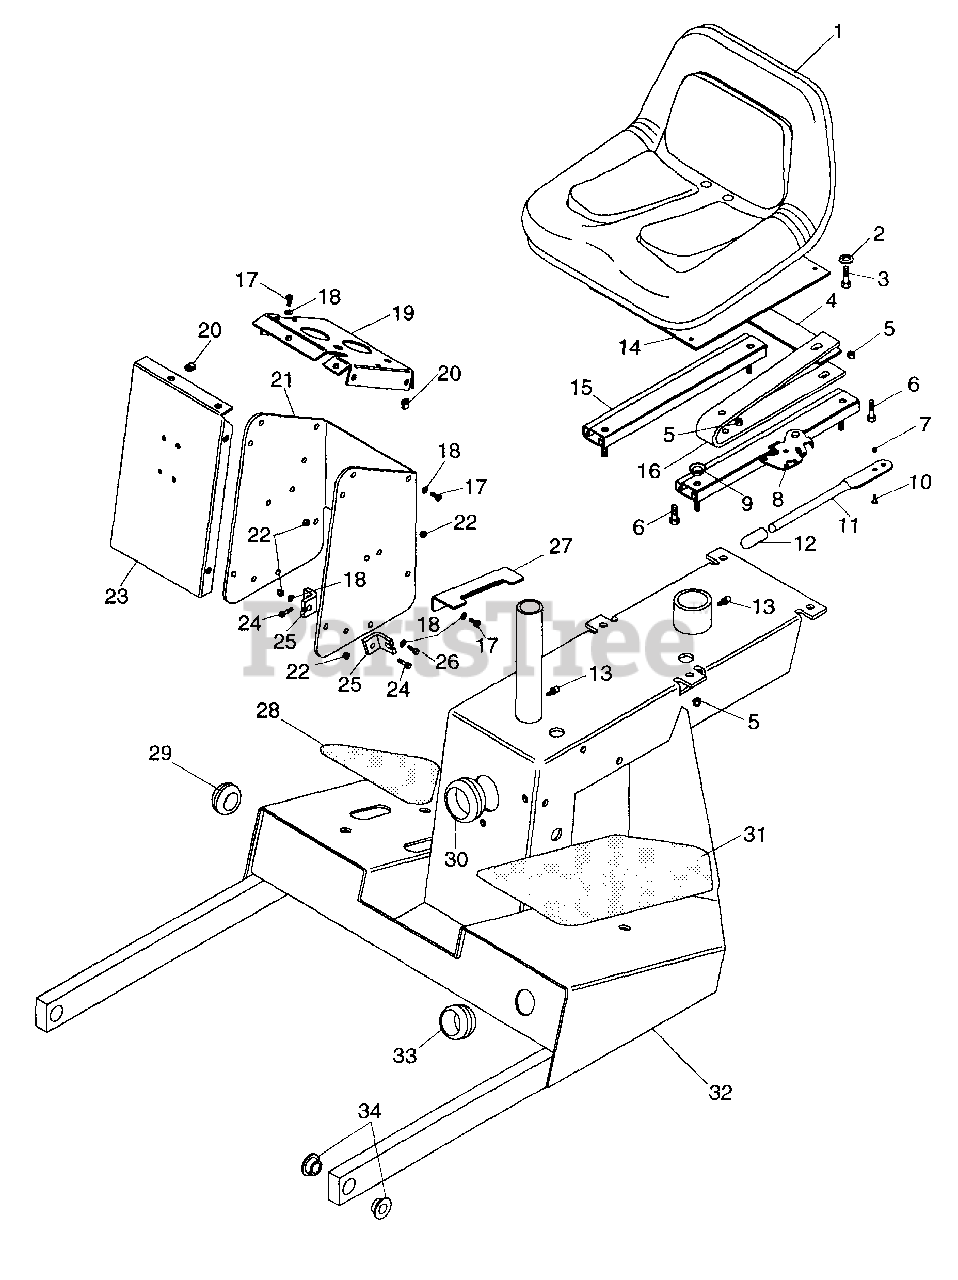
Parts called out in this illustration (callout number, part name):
1	Seat High Back
2	Washer-Lock .313 x .078
3	Bolt-Hex .31-18 x 1.00 Grade 5
4	Bracket, Seat
5	Nut-Locking-Nylon .312-18
6	Bolt-Hex .31-18 x 1.38
7	Nut-Locking 10-24
8	Adjuster, Seat w/ Latch
9	Seat Slide Spacer
10	Screw-Machine 10-24 x .625
11	Seat Slide Handle
12	Tip - Brake Lock Lever
13	Fitting-Lube .25-28 x .256
14	Plate
15	Adjuster, Seat
16	Spring, Seat
17	Screw-Machine .25-20
18	Washer-Flat-Steel .281 x .625 x .065
19	Silkscreen, Control Panel
20	Nut-Retainer .25-20 x .56
21	Support, Panel
22	Nut-Locking-Nylon .250-20
23	Panel, Silkscreen Cover
24	Bolt-Hex .25-20 x 1.00 Grade 5
25	Bracket, Cable
26	Bolt-Hex .25-20 x .75 Grade 5
27	Silk Screen Brake Stop
28	Cover, Footboard Left Hand
29	Grommet 1.25 x 1.5 x 1.81
30	Grommet
31	Cover, Footboard Right Hand
32	Weldment, Rear Frame
33	Grommet 1.50 x 1.75 x 2.12
34	Bushing-Flange .762 x 1.0 x .580 x 1.48
